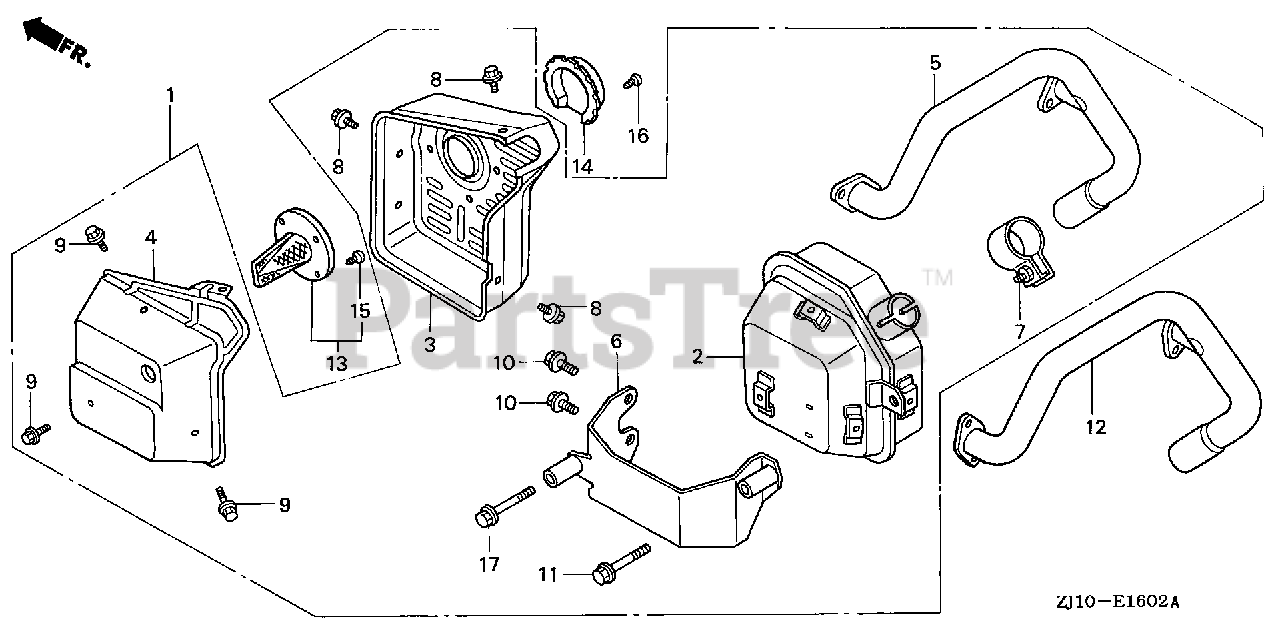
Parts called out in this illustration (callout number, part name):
13	ARRESTER, SPARK
14	DEFLECTOR KIT, EX.
15	SCREW (NELSON)
16	SCREW, TAPPING (4X8)
